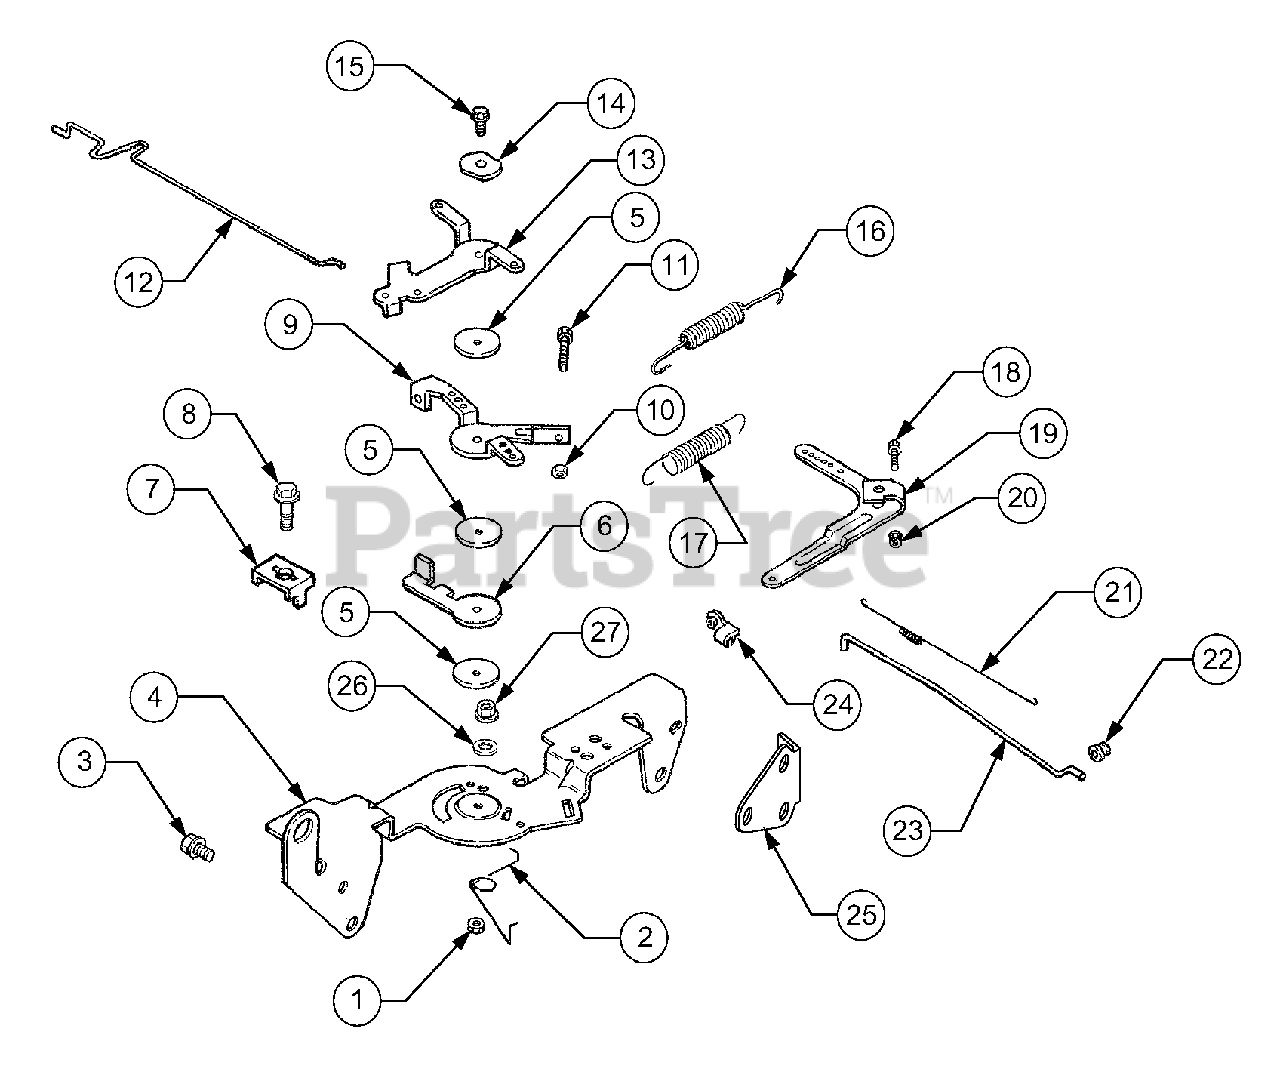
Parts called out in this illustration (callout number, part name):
1	Nut, Hex Lock M5 x 0.8
2	Spring, Choke Return
3	Screw, Hex Flange M6 x 1.0 x 16
4	Bracket, Control
5	Washer , Plain 5.5mm
6	Lever, Throttle Actuator
7	Clamp, Cable
8	Screw, Hex Flange M5 x 0.8 x 16
9	Lever, Throttle Control
10	Nut, Hex M4 x 0.7
11	Screw, Hex Cap M4 x 0.7 x30
12	Linkage, Choke
13	Lever, Choke
14	Washer, Spring 1/4"
15	Screw, Hex Flange M5 x 0,.8 x 20
16	Spring, Throttle Limiter
17	Spring, Governor
18	Screw, Round Hd. Square Neck
19	Lever, Governor
20	Nut, Hex Flange M6 x 1.0
21	Spring, Linkage
22	Bushing, Linkage Retaining
23	Linkage, Throttle
24	Bushing, Linkage Retaining
25	Bracket, Support
